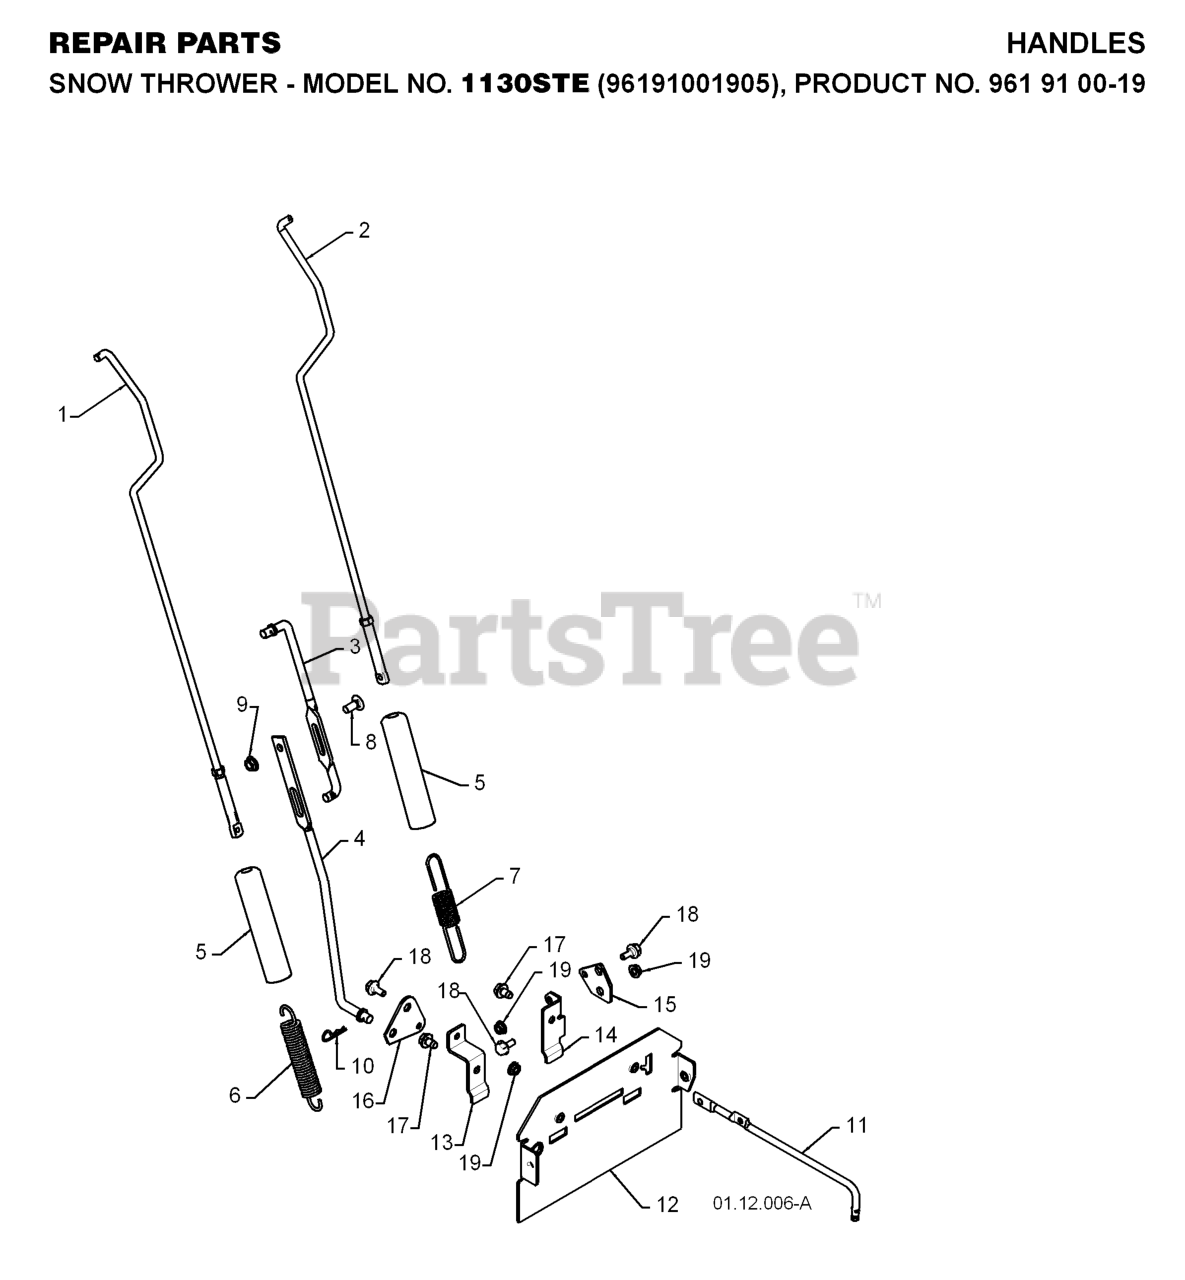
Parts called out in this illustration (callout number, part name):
1	ROD.ASM.IMPELLER
2	ROD.ASM.TRACTION
3	ROD, UPPER SPEED CONTROL
4	ROD, LOWER SPEED CONTROL.SNOW
5	SLEEVE, SPRING
6	SPRING, AUGER CONTROL
7	SPRING, TRACTION DRIVE
8	BOLT
9	NUT.FLANGE.5/16
10	SPRING RETAINER
11	ROD.CLUTCH.YELLOW.ZINC(VT)
12	PLATE.REAR.SNOW.PNT.ORANGE
13	BRACKET.SHIFTER.PLATE.BZP
14	BRACKET.CLUTCH.PLATE.BZP
15	PLATE.CLUTCH.BZP
16	PLATE.SHIFTER.BZP
17	Screw 5/16-18 x 1/2 Hex, Self Tapping 5/16-18 x 1/2
18	BOLT.SHOULDER.3/X.25
19	NUT.HEX.FLANGE.1/4
